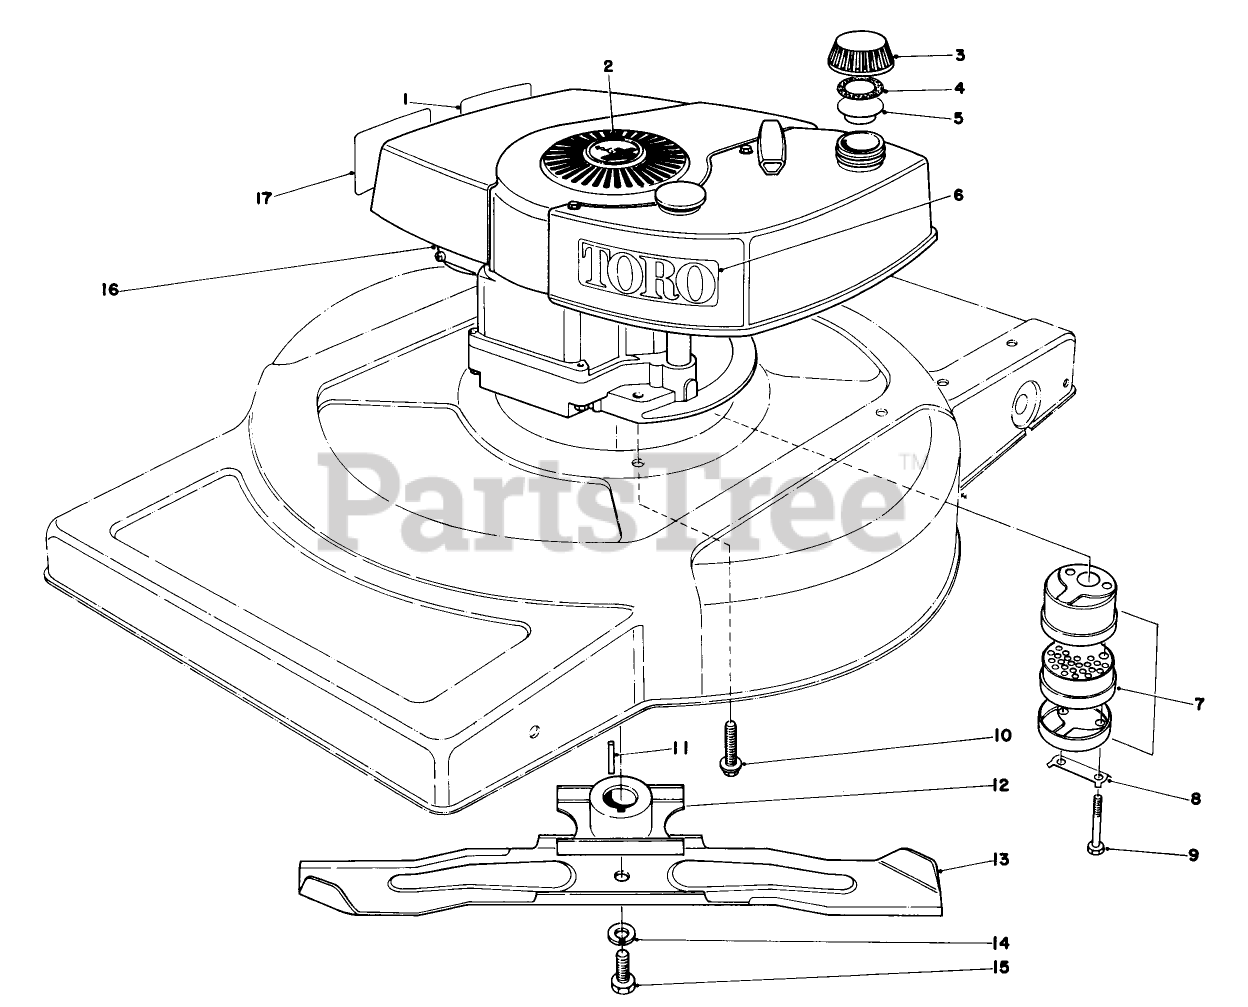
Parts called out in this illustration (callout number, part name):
1	Decal Maintenance
2	Plug Button
3	Gas Cap (Incl. Ref. #4 & 5)
4	GASKET
5	GAS CAP BAFFLE
6	Decal Toro
7	Muffler Assy. (Incl. Ref. #8 & 9
8	CLIP - LOCKING
9	SCREW-HH
10	SCREW-HWHTF
11	KEY-SQUARE
12	BLADE RETAINER WA(BLACK)
13	Blade
14	WASHER-LOCK
15	BLADE SCREW
16	Engine
17	Decal-Maintenan
